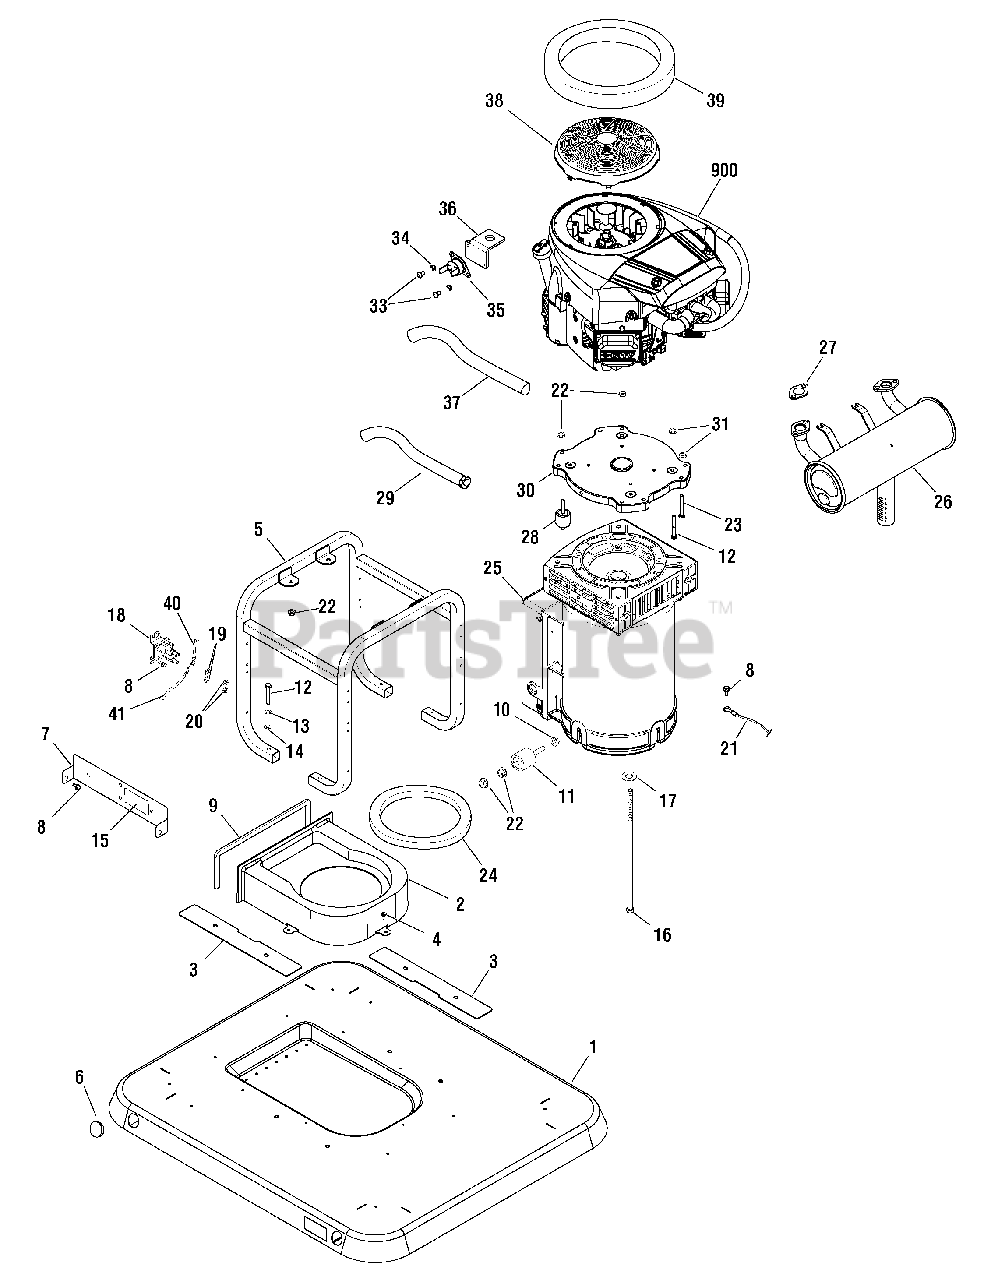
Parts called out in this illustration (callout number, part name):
8	BOLT
10	* NUT, Hex, M8 - 1.25
11	MOUNT-VIBRATION
12	* CAPSCREW, Hex Head, 5/16-18 x 2
13	* WASHER, Lock, M8
14	* WASHER, Flat, M8
15	DECAL
18	SOLENOID-STARTER
19	* WASHER, Lock, 1/4
20	* NUT, 1/4-20
23	* CAPSCREW, Hex Head, 5/16-18 x 2-1/2
24	SEAL
25	ALTERNATOR
28	MOUNT-VIBRATION
33	SCREW
36	PLATE-TEMP SWITCH
900	** ENGINE
